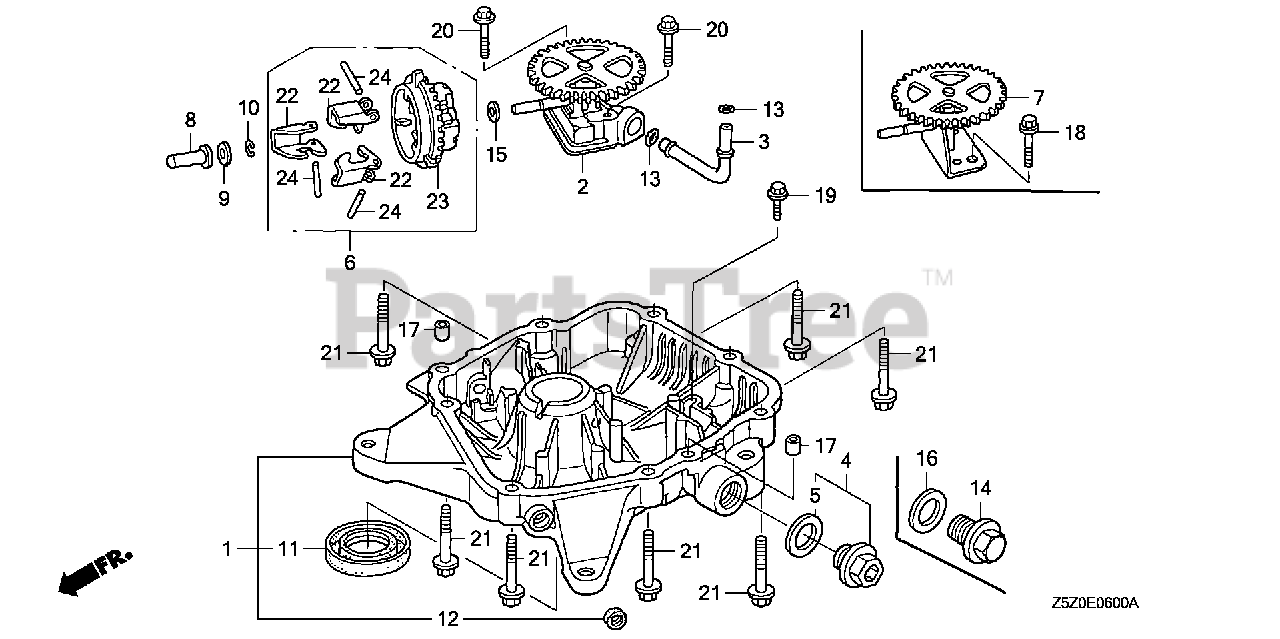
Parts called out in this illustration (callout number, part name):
1	PAN ASSY., OIL
6	GOVERNOR ASSY.
7	SHAFT, GOVERNOR
8	SLIDER, GOVERNOR
9	WASHER (6X16)
10	CLIP, GOVERNOR HOLDER
11	OIL SEAL (31X50X8)
12	OIL SEAL (10X16X4.5)
14	BOLT, DRAIN PLUG (20MM)
15	WASHER, PLAIN (6MM)
16	WASHER, DRAIN PLUG (20MM)
17	PIN A, DOWEL (8X14)
18	BOLT, FLANGE (6X16) Use from Engine SN 2056820.
21	BOLT, FLANGE (8X40) Use up to Engine SN 1003236.
22	WEIGHT, GOVERNOR
23	HOLDER, GOVERNOR WEIGHT
24	PIN, GOVERNOR WEIGHT
